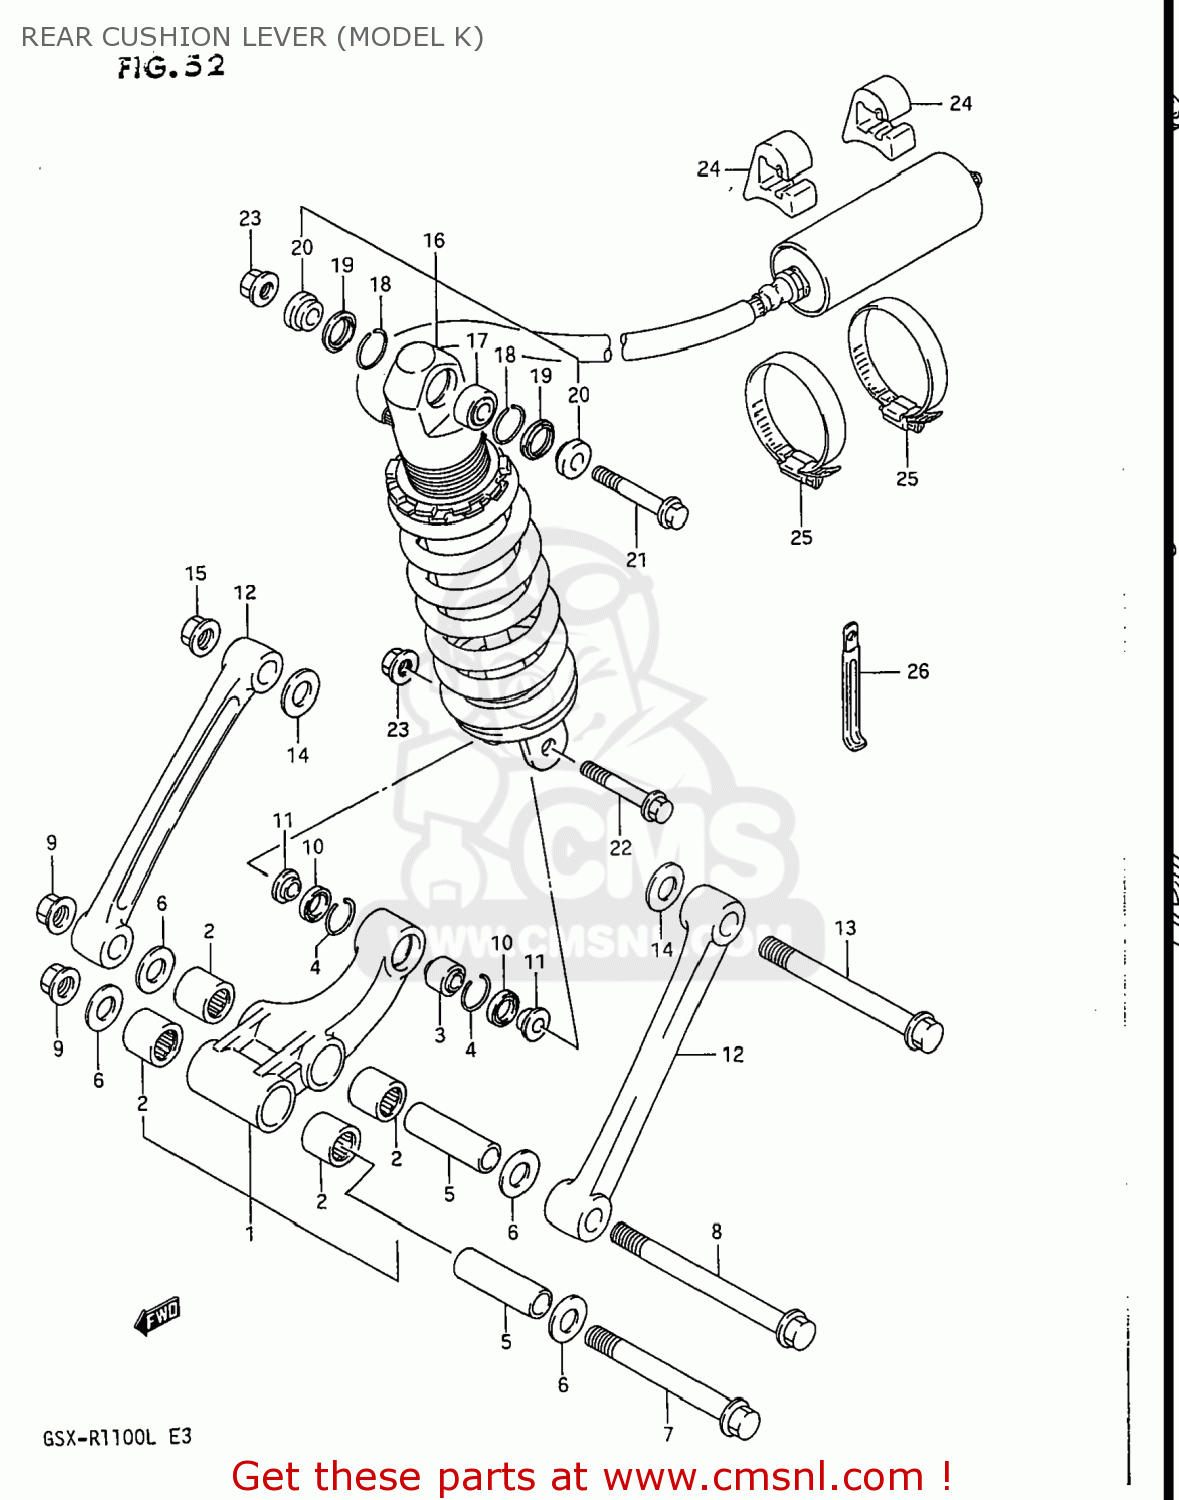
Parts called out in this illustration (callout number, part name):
1	LEVER SET,REAR CUSHION
2	BEARING(20X27X23.5)
3	BEARING,RR CUSHION LEVER
4	RING,STOPPER
5	SPACER,RR CUSHION LEVER
6	WASHER
7	SHAFT,RR CUSHION LEVER FR
8	SHAFT,RR CUSHION ROD
9	NUT
10	DUST SEAL,RR CUSHION LEVER RR
11	SPACER
12	ROD,REAR CUSHION
13	SHAFT,RR CUSHION ROD
14	WASHER
15	NUT
16	ABSORBER ASSEMBLY,REAR SHOCK
17	SPHERICAL BEARING,RR CUSHION
18	RING,STOP
19	SEAL DUST
20	COLLAR
21	BOLT
22	BOLT(10X60)
23	NUT
24	CUSHION,RESERVOIR TANK
25	CLAMP
26	CLAMP
